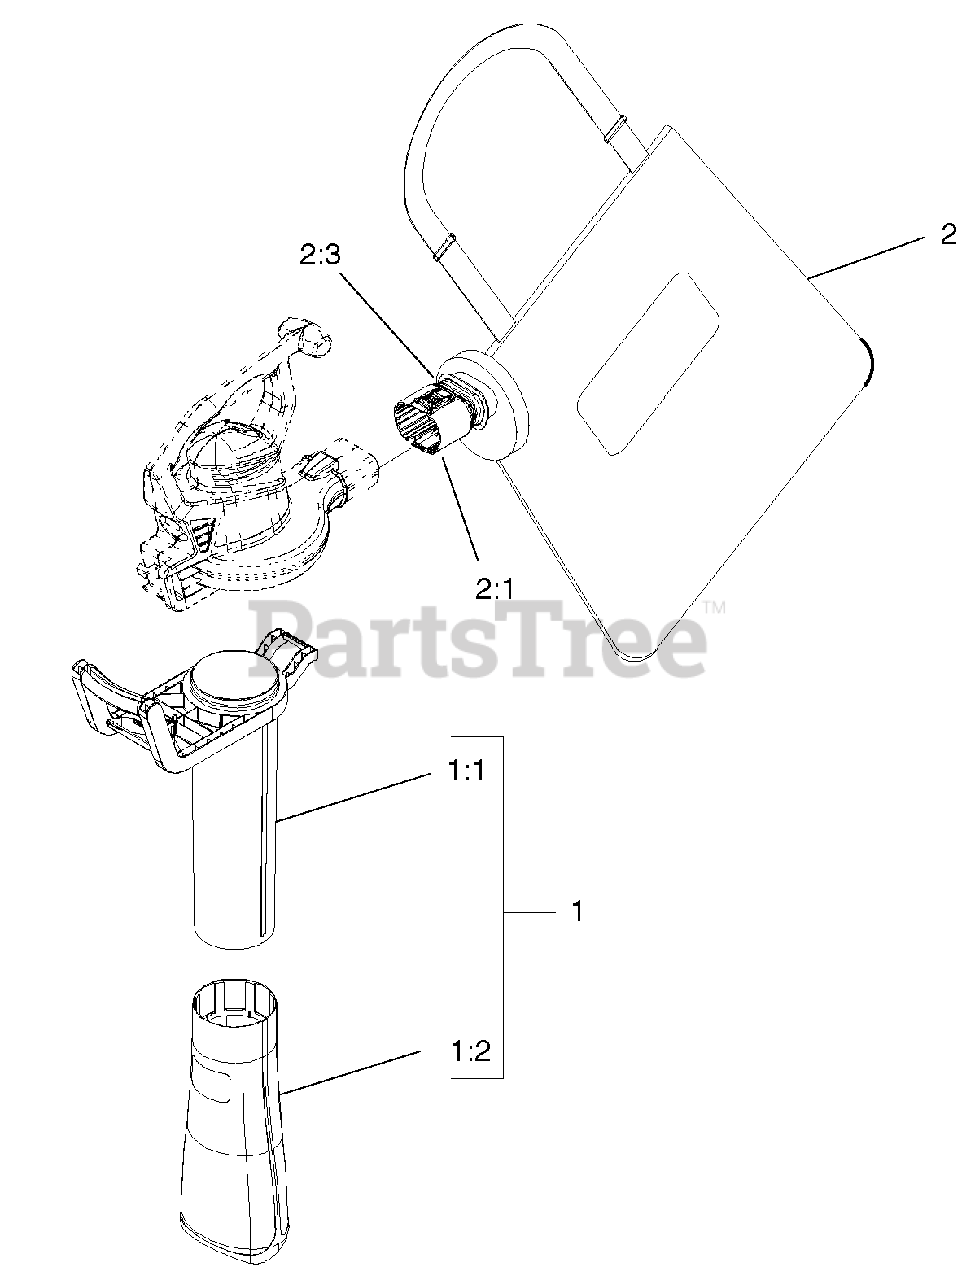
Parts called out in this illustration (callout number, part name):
1	VAC TUBE ASM
1:1	TUBE-VAC, UPPER
1:2	TUBE-VAC, LOWER
2	BAG ASM
2:1	COLLAR-BAG
2:3	TIE-CABLE
